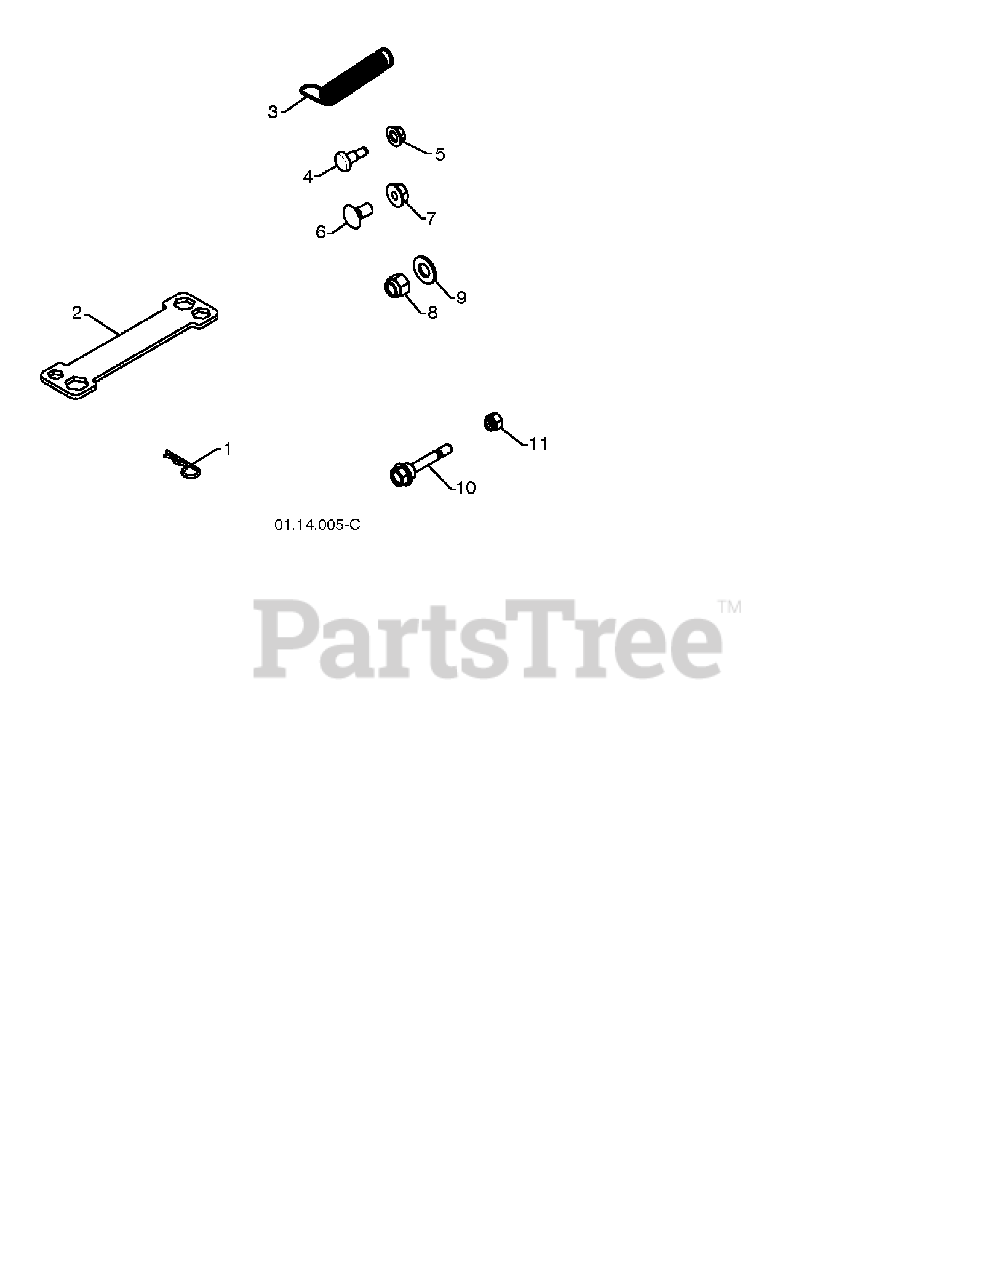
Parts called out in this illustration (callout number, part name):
1	SPRING RETAINER
2	WRENCH.SNOWTHROWER
4	BOLT, SHOULDER
5	NUT.HEX.FLANGE.1/4
6	BOLT
7	NUT, LOCK 5/16-18
8	NUT
10	BOLT, SHOULDER SHEAR
11	LOCKNUT
